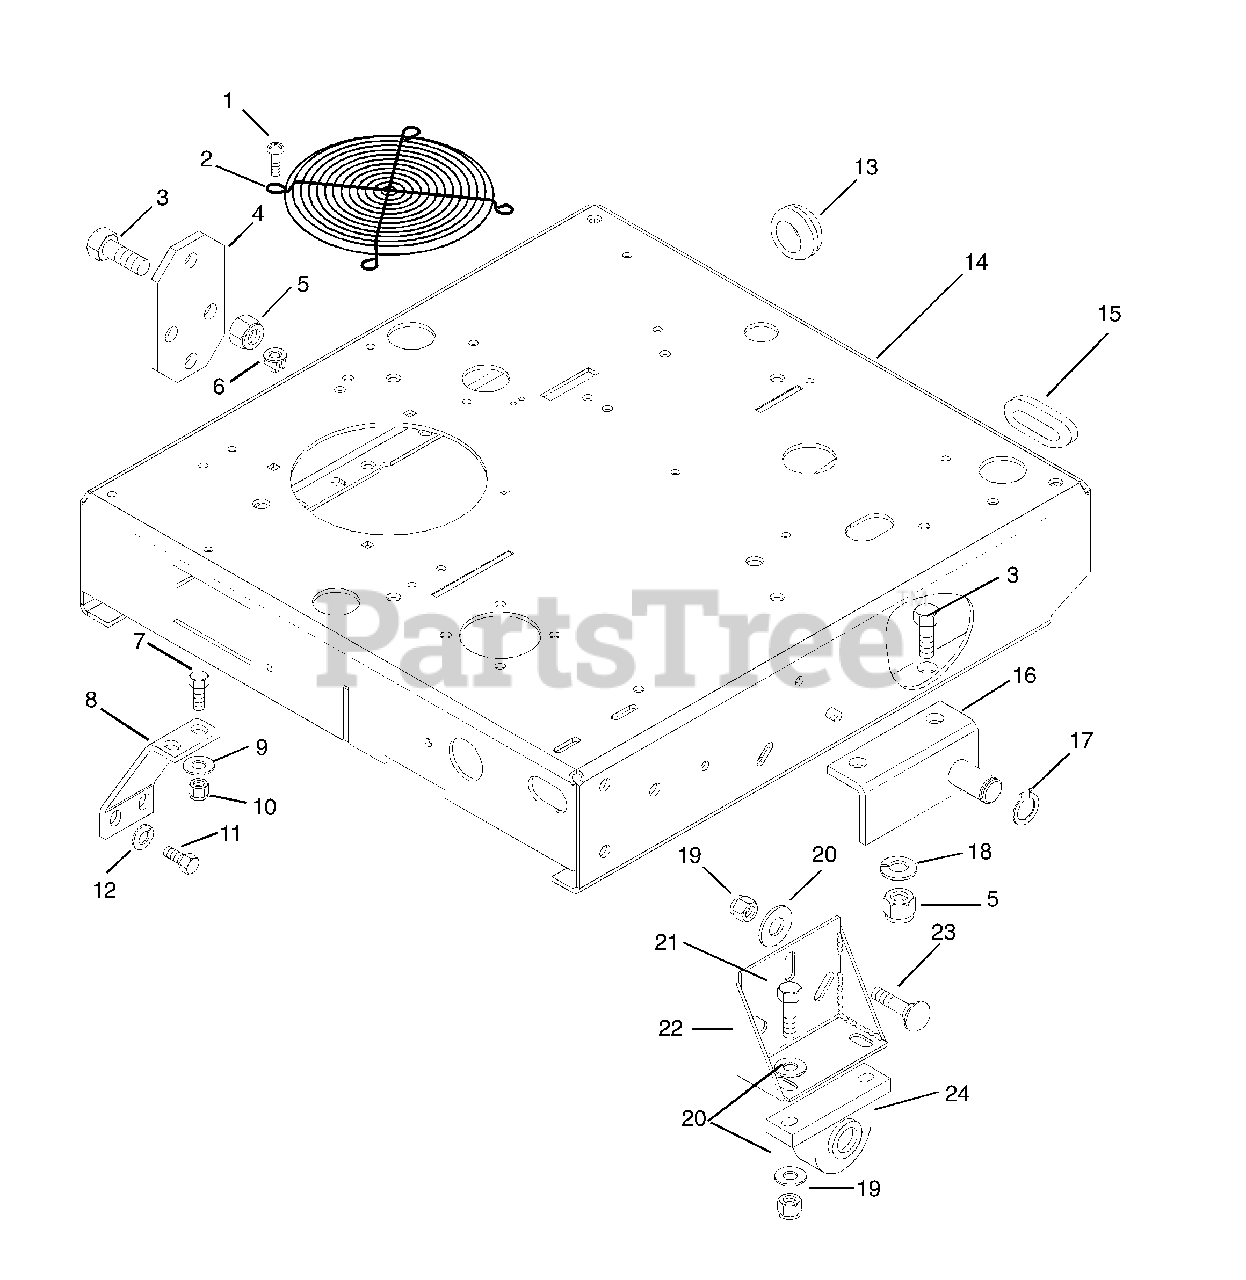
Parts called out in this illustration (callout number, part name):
1	Screw-Tapping .25-20 x .50
2	Guard Fan
3	Bolt-Hex .50-13 x 1.50 Grade 5
4	Plate
5	Nut-Locking-Center .50-13
6	Grommet-Plastic
7	Bolt-Hex .38-16 x 1.00 Grade 5
8	Bracket-Transaxle Support
9	Washer-Flat-Steel .344 x .688 x .065
10	Nut-Locking-Center .38-18
11	Bolt-Hex .31-18 x .75 Grade 5
12	Washer-Lock .31 x .078
13	Grommet 1.50 x 1.75 x 2.12
14	Weldment-Frame
15	Grommet .63 x .687 x 1.25
16	Weldment-Pivot Left Hand
16	Weldment-Pivot Right Hand
17	Ring-Retaining-External .689 x .077
18	Washer-Lock .50 x .125
19	Nut-Locking-Center .38-16
20	Washer-Flat-Steel .406 x .812 x .065
21	Bolt-Hex .38-16 x 1.50 Grade 5
22	Weldment-Axle Support
23	Bolt-Round Head Square Neck .38-16 x 1.00
24	Bearing-Pillow Block 1.0 x 2.688 x 6.188
